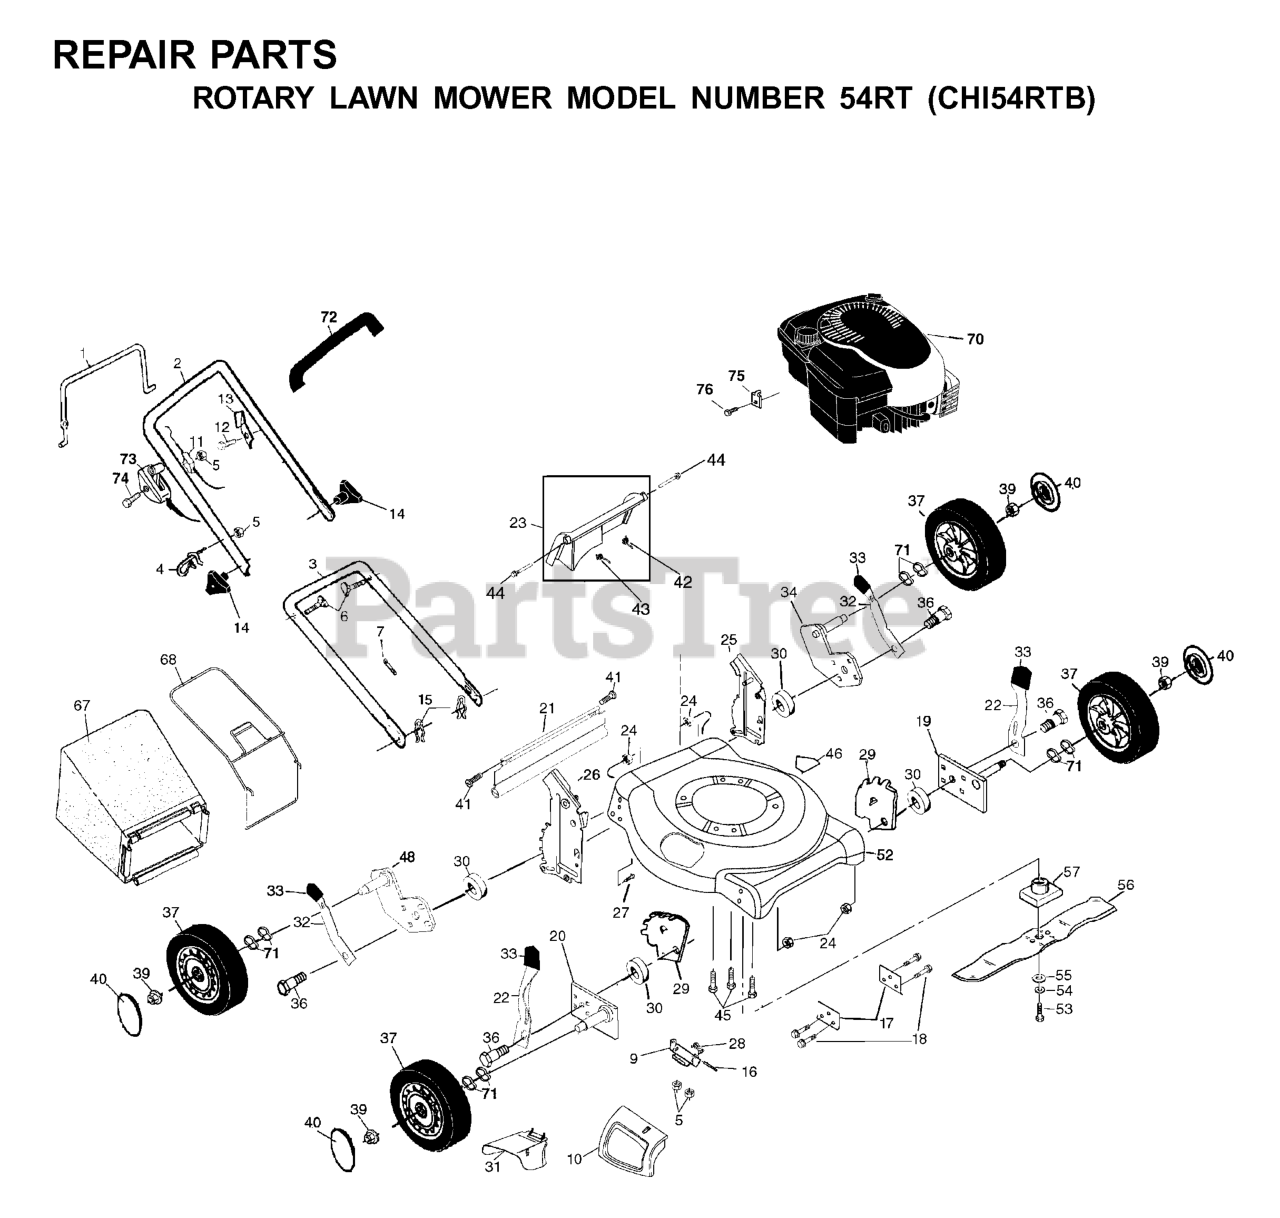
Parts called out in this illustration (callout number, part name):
1	CONTROL BAR
3	HANDLE.LOWER.BLACK
4	ROPE GUIDE
5	NUT
6	HANDLE BOLT
7	TIE GUIDE
9	BRACKET.ASM.HOUSING.EZ.MUL
10	MULCH DOOR
11	CABLE.MZR.51.RT.SP./PU.
12	TAPPING SCREW
13	BRACKET UPSTOP
15	HAIRPIN COTTER
16	ROD.HINGE.COMBI-C
17	SUPPORT BRACKET
18	SCREW 1/4X20
19	AXLE ARM ASM (L)
20	AXLE ARM ASM
21	REAR DEFLECTOR, POULAN PR6N22
22	REPL BY 532 1683-60
23	REAR DOOR ASSEMBLY KIT
24	NUT.LOCK.5/16-18
25	HANDLE BRACKET ASSEMBLY, LEFT
26	HANDLE.BRKT.ASSY.RIGHT.BLACK
27	SCREW
28	TORSION SPRING
29	WHEEL BRACKET ADJUSTER
30	WASHER
31	CLIP ON DISCHARGE GUARD
36	SHOULDER BOLT
37	WHEEL ASMBLY FRONT
39	HEX FLANGE LOCKNT
40	CAP.HUB.ARC.SPOKE.8".LP
41	HINGE SCREW
42	SPRING (LH)
43	SPRING (RH)
44	DOOR BOLT
45	BOLT 3/8-16X1-1/8
46	DECAL HYT
52	HOUSING ASSEMBLY
53	SCREW, HEX HD 3/8-24 X 1-3/8
54	LOCKWASHER
55	WASHER,HARDEN
56	21" PUSH BLADE
57	BLADE ADAPTOR
71	WAVE WASHER
72	GRIP.HANDLE.FOAM
73	THROTTLE CONTROL
74	SCREW 1/4-20 X 2.12
75	CABLE CLAMP(ENGINE)
76	SCREW.HEX.HEAD.WASHER.10-16
